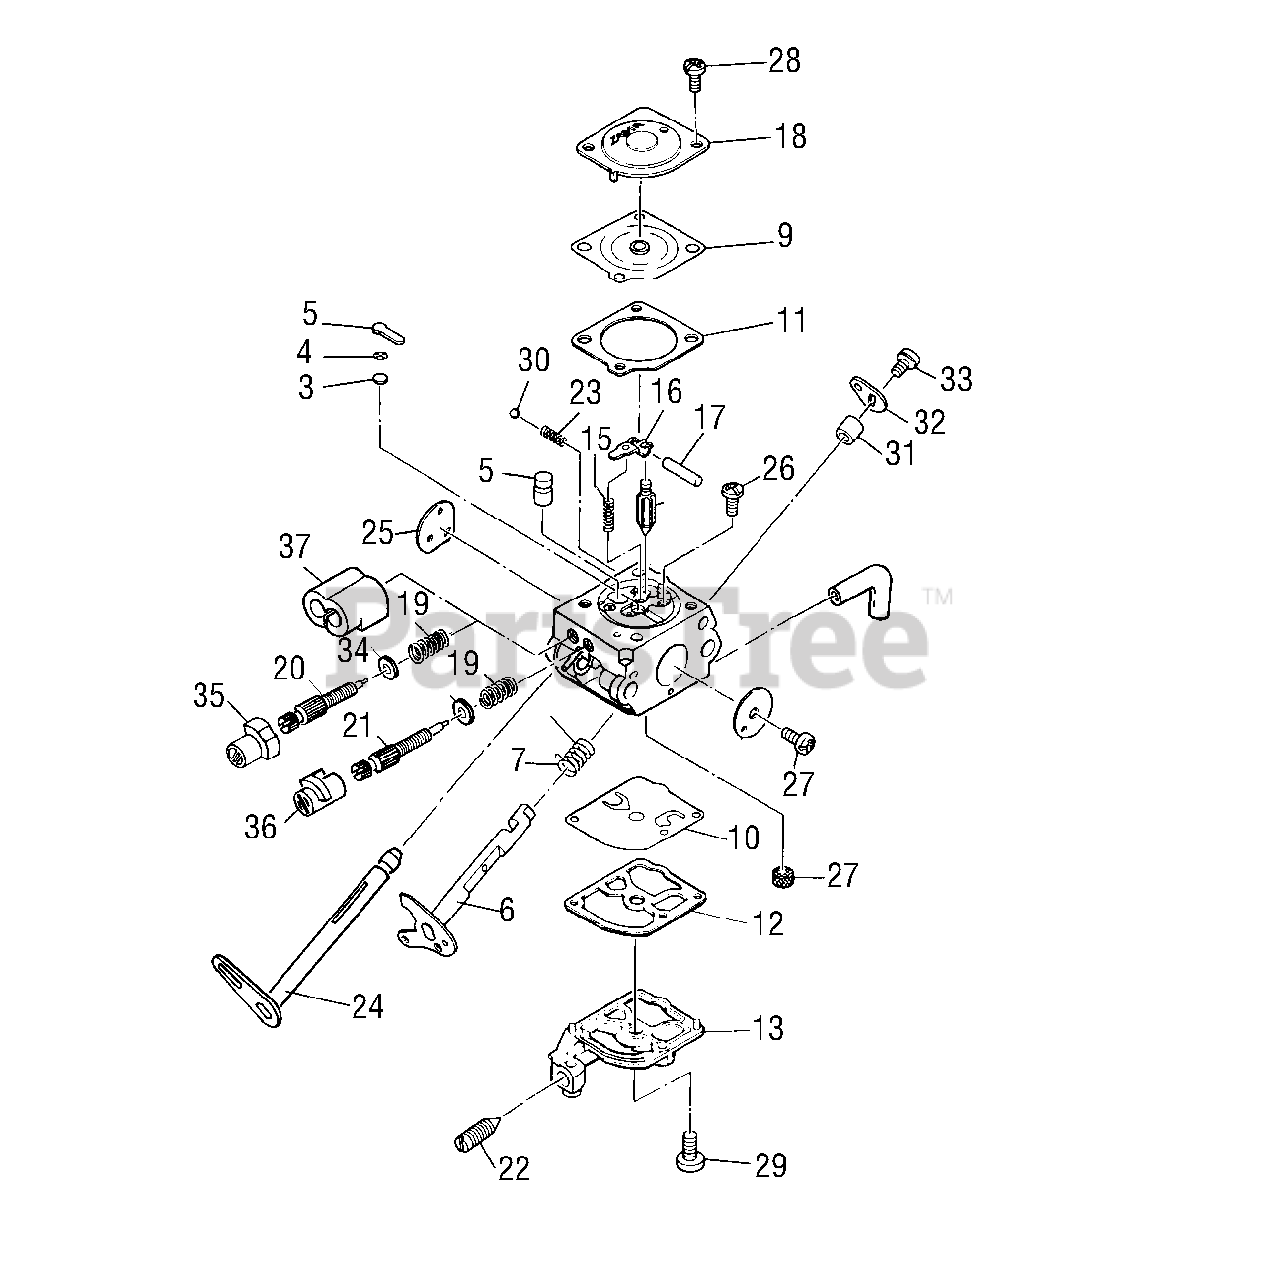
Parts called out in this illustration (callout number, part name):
1	Strainer
2	Plug, Welch
3	Valve, Check
4	Retainer, Check Valve
5	Nozzle Asy, Check Valve
6	Shaft Asy, Throttle
7	Spring, Throttle Return
8	Valve, Throttle
9	Diaphragm Asy, Metering
10	Diaphragm, Pump
11	Gasket, Metering Chamber
12	Gasket, Pump
13	Cover, Pump
14	Valve, Inlet Needle
15	Spring, Metering Lever
16	Lever, Metering
17	Pin
18	Cover, Metering Chamber
19	Spring, Adjust Screw
20	Screw, Main Mixture
21	Screw, Idle Mixture
22	Screw,Throttle Adjust
23	Spring, Friction
24	Shaft Asy, Choke
25	Valve, Choke
26	Screw, Pin
27	Screw, Throttle/Choke Valve
28	Screw, Metering Chamber
29	Screw, Pump Cover
30	Ball, Steel
31	Collar
32	Lever, Throttle
33	Screw, Throttle Lever
34	Washer, Limiter
35	Cap, Limiter, Hi
36	Cap, Limiter, Lo
37	Retainer, Limiter
